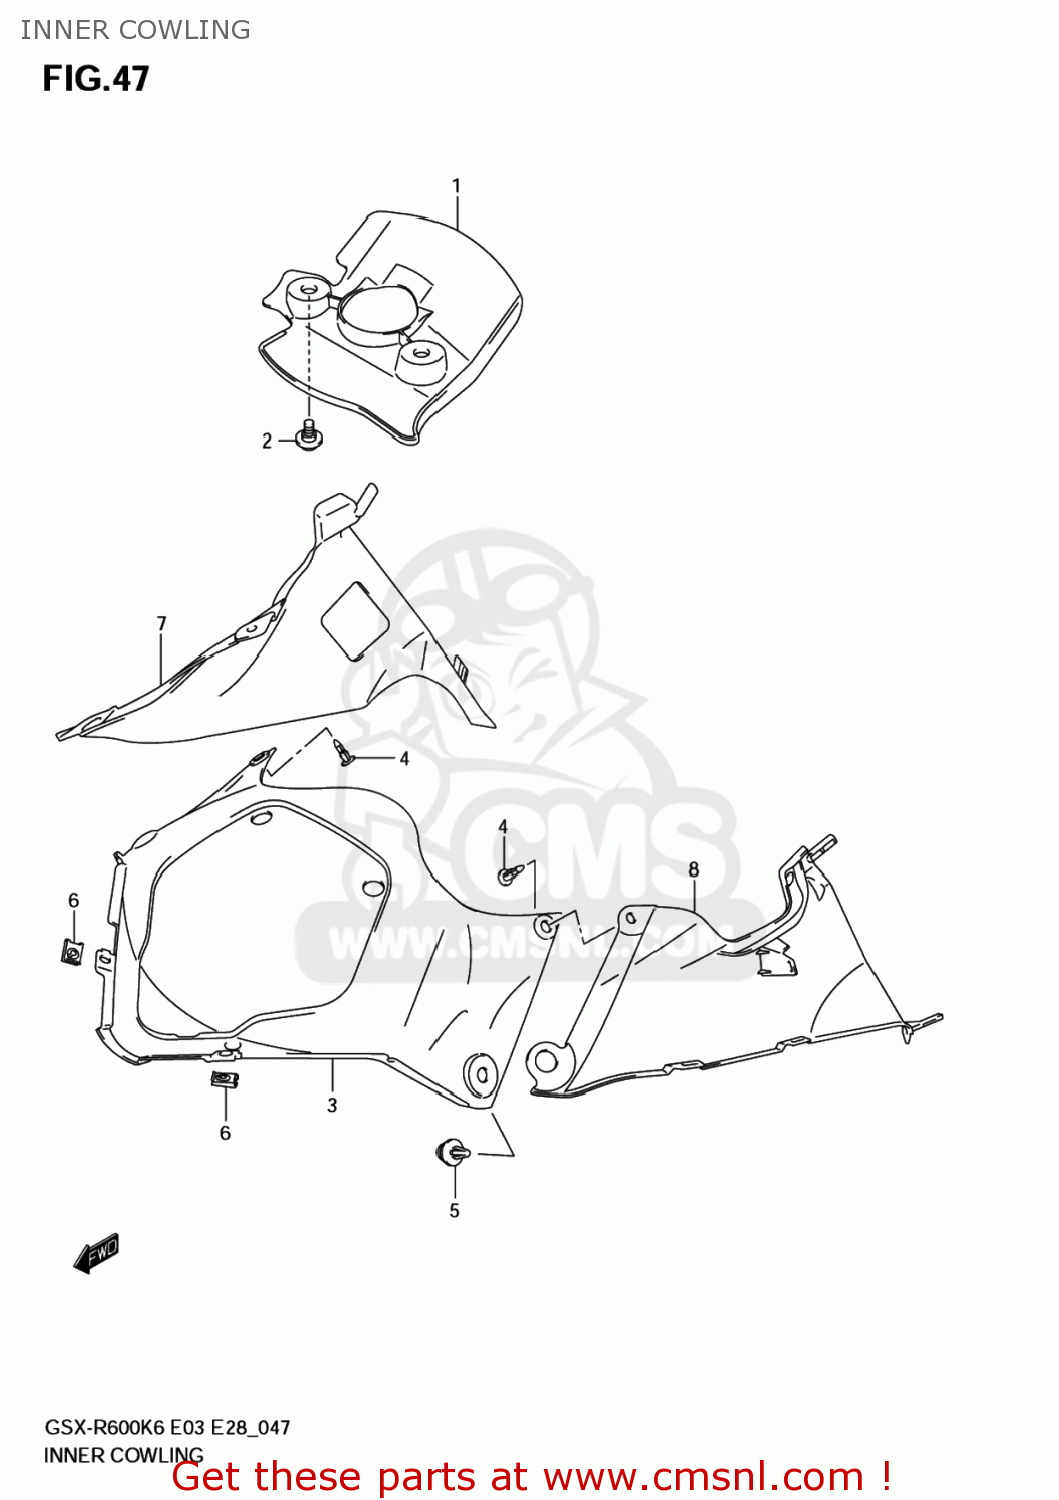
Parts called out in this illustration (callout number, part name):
1	COVER,LWR BRACKET
2	BOLT
3	COVER,BODY COWLING
4	CLIP(BLACK)
5	CLIP
6	NUT
7	COWLING,UNDER INNER,R
8	COWLING,UNDER INNER,L
